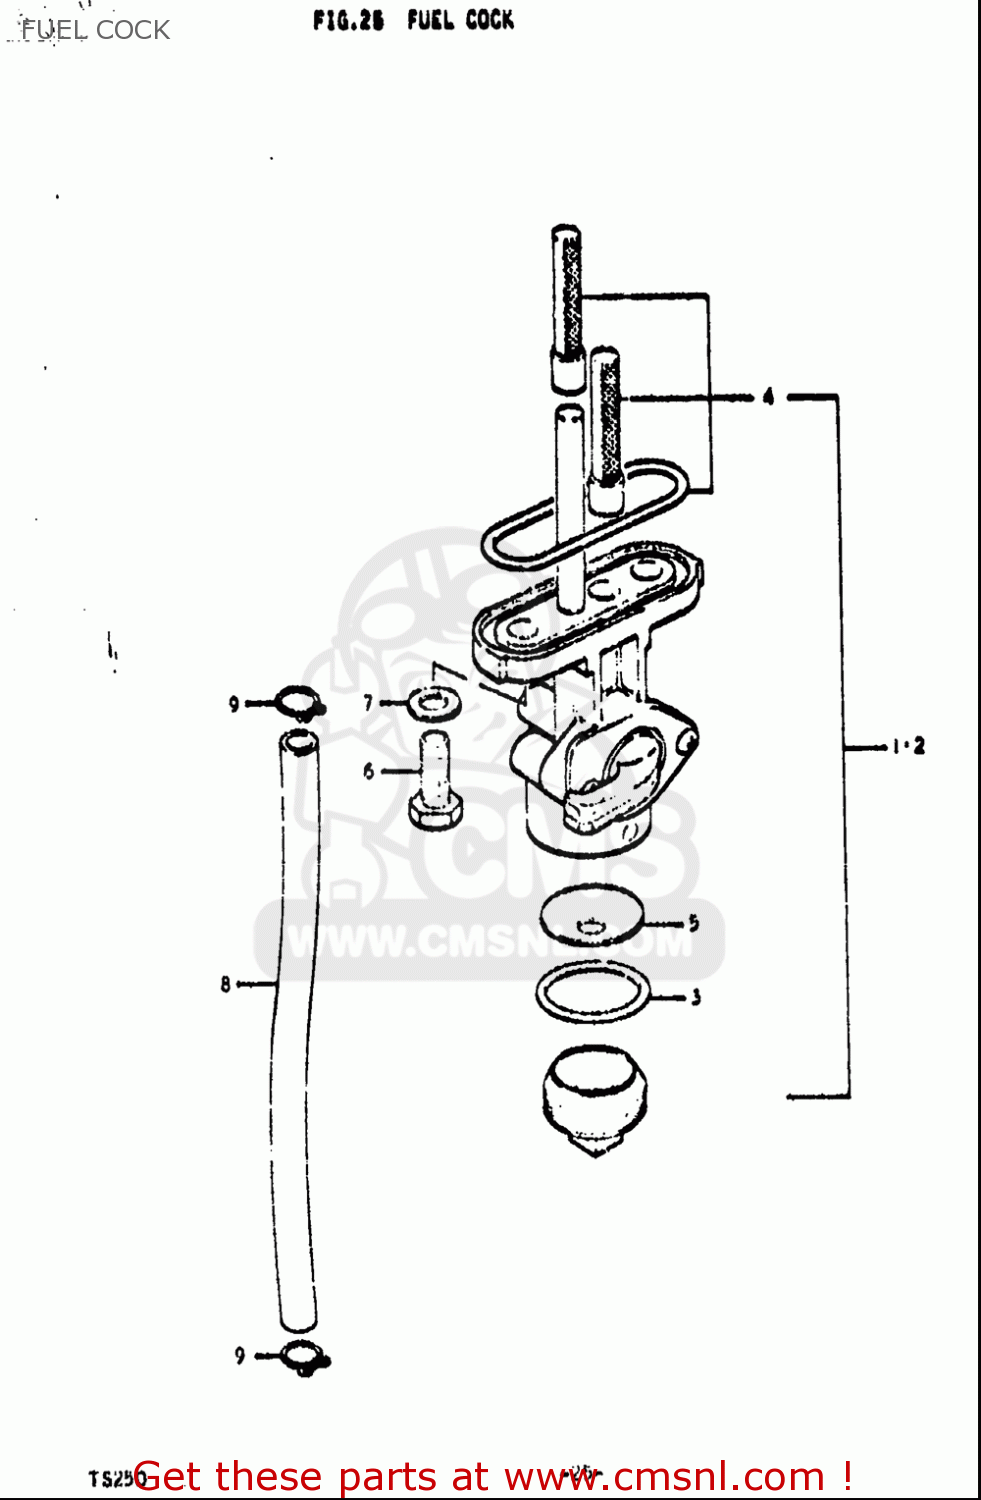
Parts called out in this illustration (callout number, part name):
1	COCK ASSY,FUEL
2	COCK ASSY,FUEL
3	GASKET,FILTER (NAS)
4	FILTER SET,FUEL COCK
5	NET,STRAINER
6	BOLT(8X11)
7	GASKET(5.8X13X1.2) (NAS)
8	HOSE(5X8.2X600)
9	CLIP
